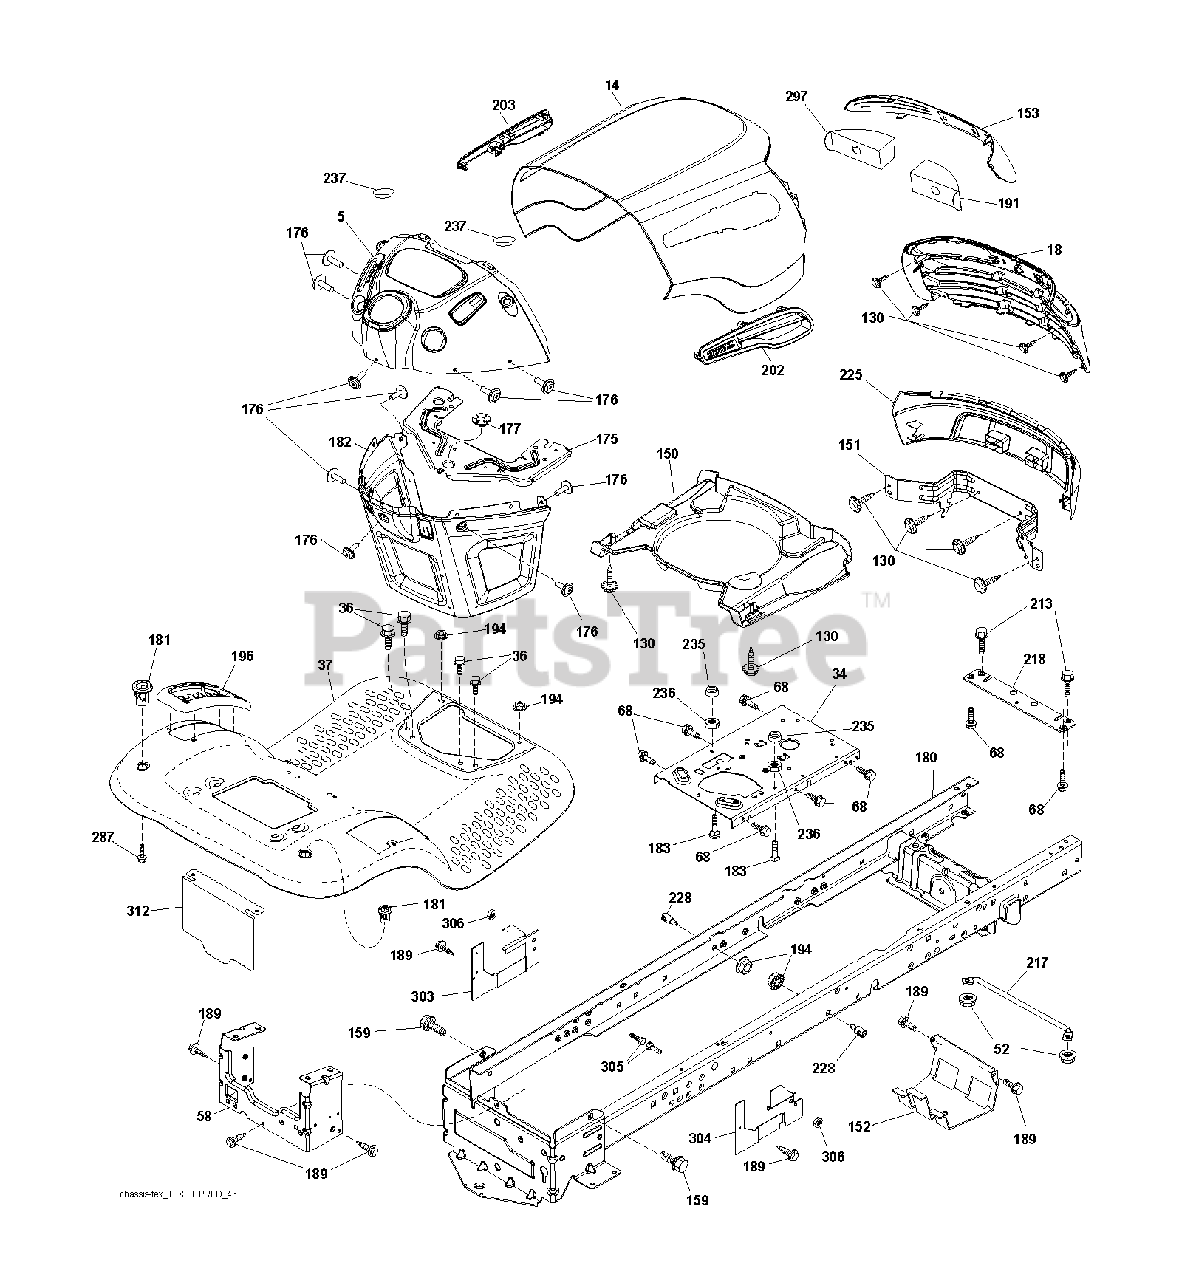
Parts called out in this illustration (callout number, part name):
34	PLATE.ENGINE.WELDED.CHASSIS
36	SCREW 5/16"
52	LOCKNUT
58	DRAWBAR UPPER 2PC SMALL FENDER
130	SCREW.#10 X 0.750.BOS THREAD
151	BRACKET.PIVOT.ALPHA.LT
152	SHIELD BROWNING
159	SCREW, 3/8-16X3/4
175	CROSSMEMBER
176	SCREW.#10-24X5/8.RN.QU
177	BUSHING STEERING
180	CHASS.WLDMNT.TL.12GA/2P.48/54
181	FEND/FTRST.PCH.CPH.NFW
182	DASH.LWER.PREDATOR/HUSQ.LT
183	BOLT.5/16-18X1-1/4 FULL THD
189	SCREW
191	INSERT.REFLECT.PREDATOR.LT.RH
194	NUT LOCK HEX FLANGE 5/16-18
196	CONSOLE.ASM.DECKLFT.BL/RBT.TLT
213	BOLT
217	ROD.PIVOT.HOOD
218	X-PIECE.HOOD.STOP.NON/
228	STUD.FASTNER.W/ANTI-ROTATE
235	SPACER FENDER
236	NUT.CENTERLOCK.5/16-
237	PLUG.MOUNT.CARGO.BLK
297	REFLECTOR.INSERT.PRED.LH.LT
306	NUT LOCK FLG 3/8-16 UNC
